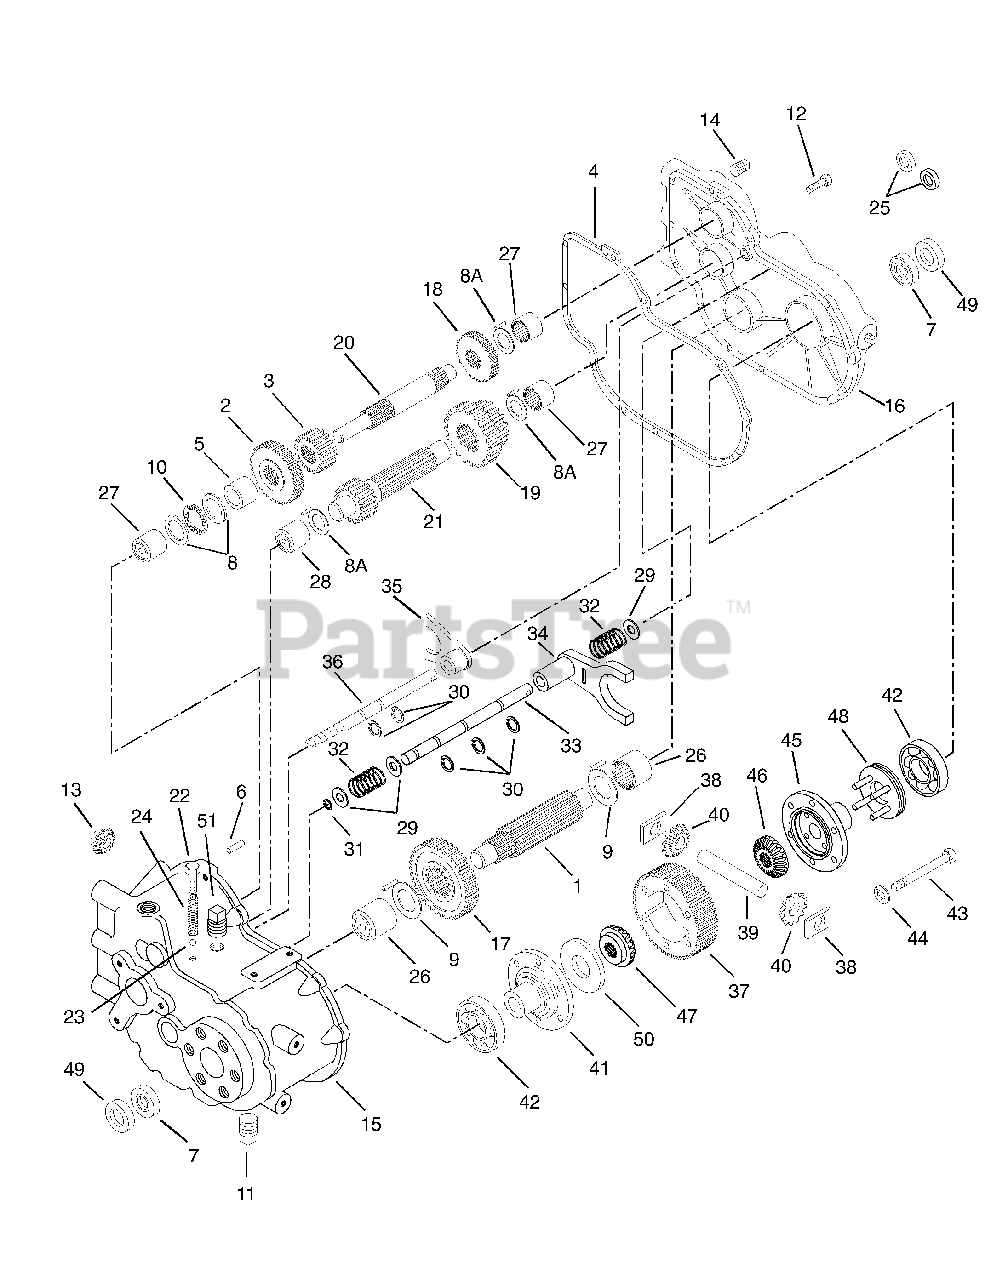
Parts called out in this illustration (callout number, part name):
1	Pinion, Output
2	Gear, Bevel (30 teeth)
3	Gear, Spur (16 teeth)
4	Gasket, Case & Cover
5	Spacer, (1-5/8" O.D. x 1-1/64" I.D. x 55/64" thick)
6	Pin. Dowel
7	Seal, Oil
8	Washer, Thrust (1.542 O.D. x 1.007 I.D. x .060 thick)
8A	Washer, Thrust (1.687 O.D. x 1.007 I.D. x .0575) (tabbed)
9	Washer, Thrust (2.187 O.D. x 1.257 I.D. x .0575) (tabbed)
10	Bearing, Thrust
11	Plug, Magnetic Drain, 3/8-18
12	Screw, Machine .31 -18 x 1 Self Tapping Hex Washer Head
13	Pinion, Bevel
14	Plug, Pipe, 1/8-27
15	Case Assembly., Transaxle
16	Cover, Assembly., Transaxle
17	Gear, Output (37 teeth)
18	Gear, Spur (23 teeth)
19	Gear, Cluster (20 & 27 teeth)
20	Shaft, Counter
21	Shaft & Gear Shifter
22	Screw, Hex Flanged Head 1/4-20 x 5/8
23	Ball, Steel, 3/16"
24	Spring, Shifter Fork
25	Seal, Oil
26	Bearing, Needle
27	Bearing, Needle
28	Bearing, Needle
29	Washer, Thrust .917 O.D. x .507 I.D. x .060
30	Ring, Retaining
31	Ring, Retaining
32	Spring, Compression
33	Rod, Shift (Differential Lock)
34	Fork, Shift
35	Fork, Shift
36	Rod, Shift (Hi-Low)
37	Gear, Ring
38	Block, Drive
39	Pin, Drive
40	Pinion, Bevel
41	Carrier, Differential
42	Bearing, Ball
43	Screw, Hex Flanged Head., 3/8-16 x 2-3/4
44	Washer-Locking, 3/8"
45	Carrier, Differential
46	Gear, Bevel
47	Gear, Bevel
48	Collar Assembly, Shift
49	Spacer (2-1/8" O.D. x 1-5/32 I.D. x 3/8" thick)
50	Washer, Thrust
51	Plug, 3/8-18 Square Head Pipe
